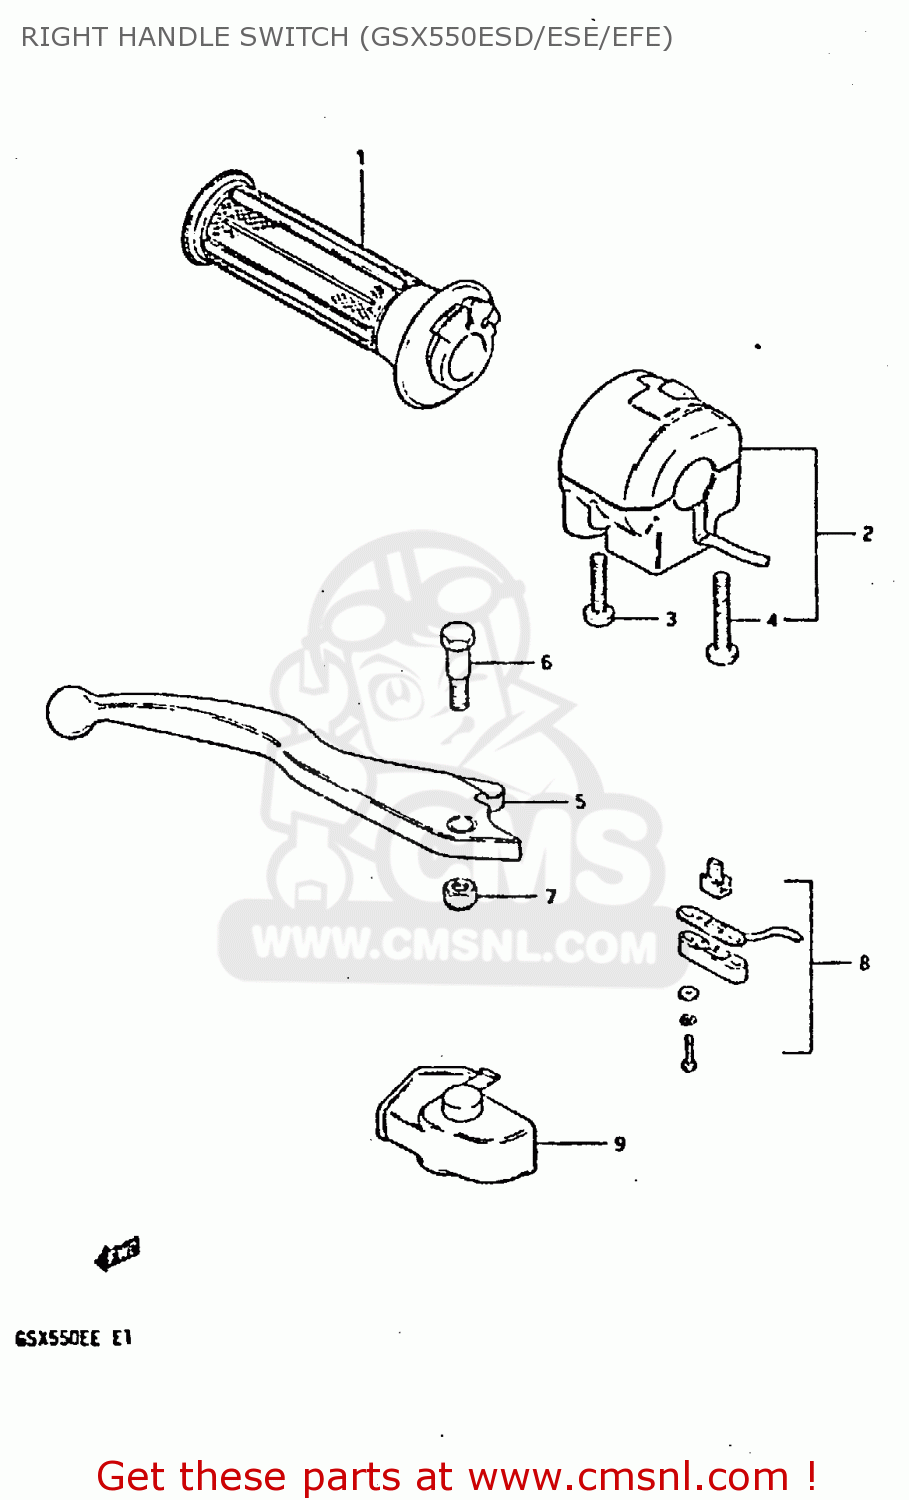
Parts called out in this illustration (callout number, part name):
1	GRIP,THROTTLE
2	SWITCH ASSEMBLY,HANDLE,RIGHT
3	SCREW
4	SCREW
5	LEVER,BRAKE
6	BOLT,LEVER PIVOT
7	NUT 6MM
8	SWITCH ASSEMBLY
9	COVER,BRAKE LEVER
